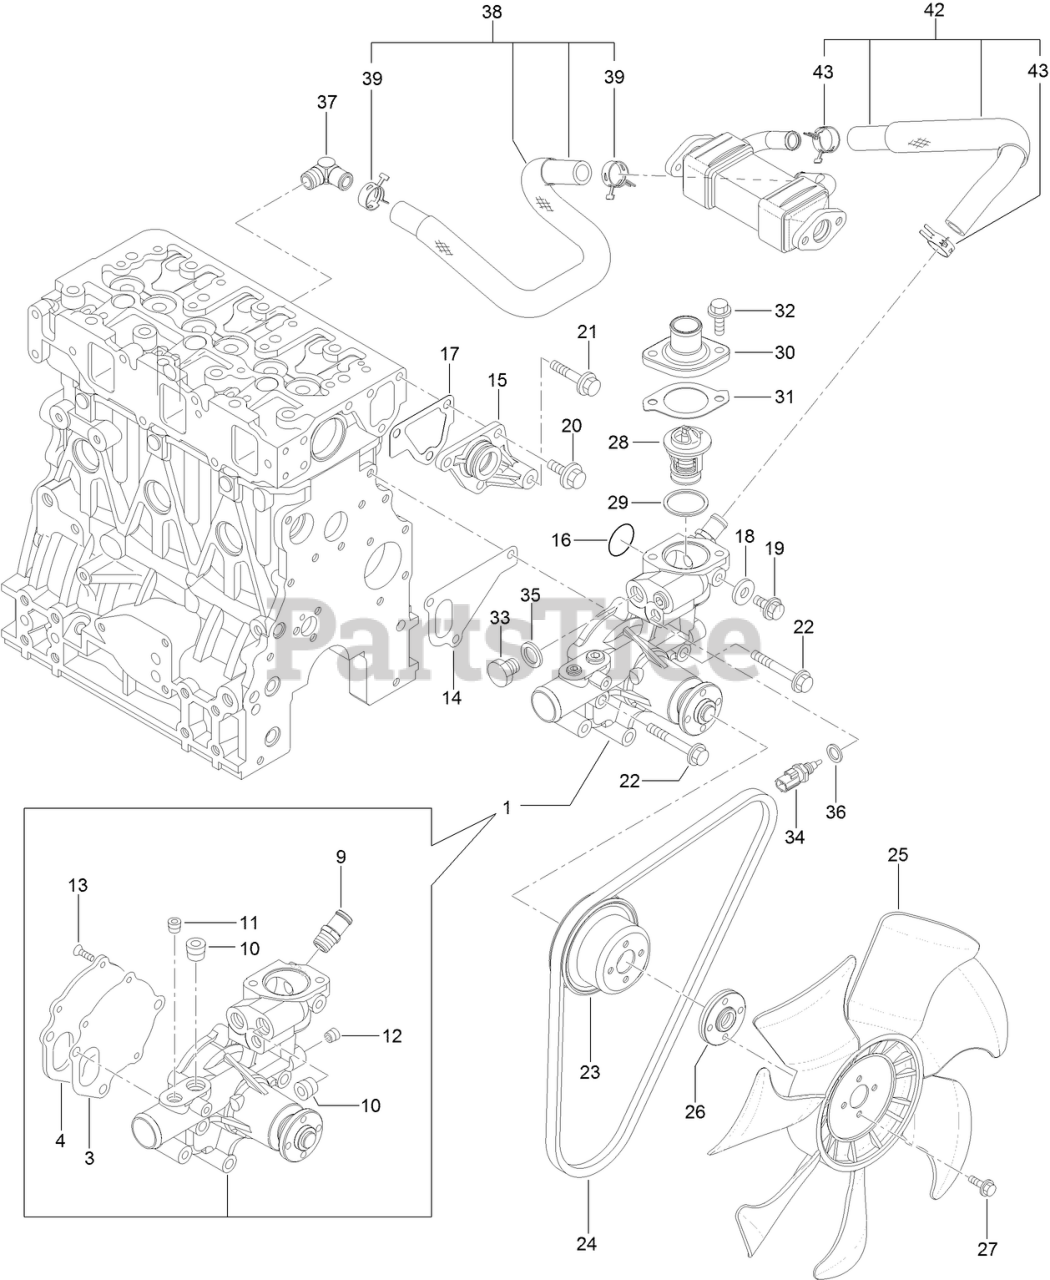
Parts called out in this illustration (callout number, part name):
1	WATER PUMP ASM
3	GASKET
14	GASKET
16	O-RING
17	GASKET
18	GASKET
20	BOLT
23	V-PULLEY
24	V-BELT
26	SPACER
28	THERMOSTAT
29	GASKET
31	GASKET
34	SENSOR-THERMOSTAT, CW
35	GASKET
36	WASHER-SEAL
38	E G R-C PIPE ASM
39	CLIP-HOSE
42	CW PIPE ASM
43	CLIP-HOSE
